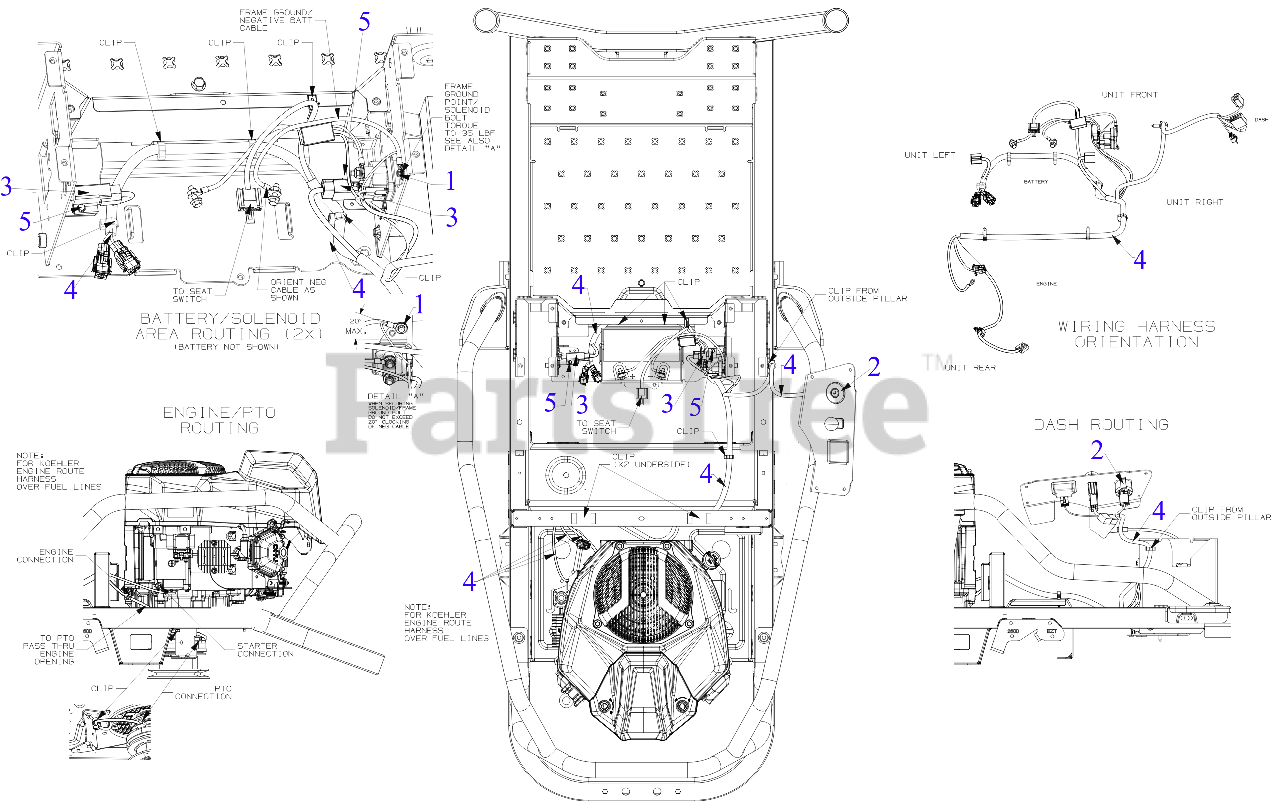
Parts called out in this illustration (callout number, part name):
1	SCREW M6-1 x .625
2	KEY SWITCH 3 POS
3	INTERLOCK SWITCH (NO/NC)
4	MAIN HARNESS
4	12V SOLENOID
5	SHOULDER SCREW
